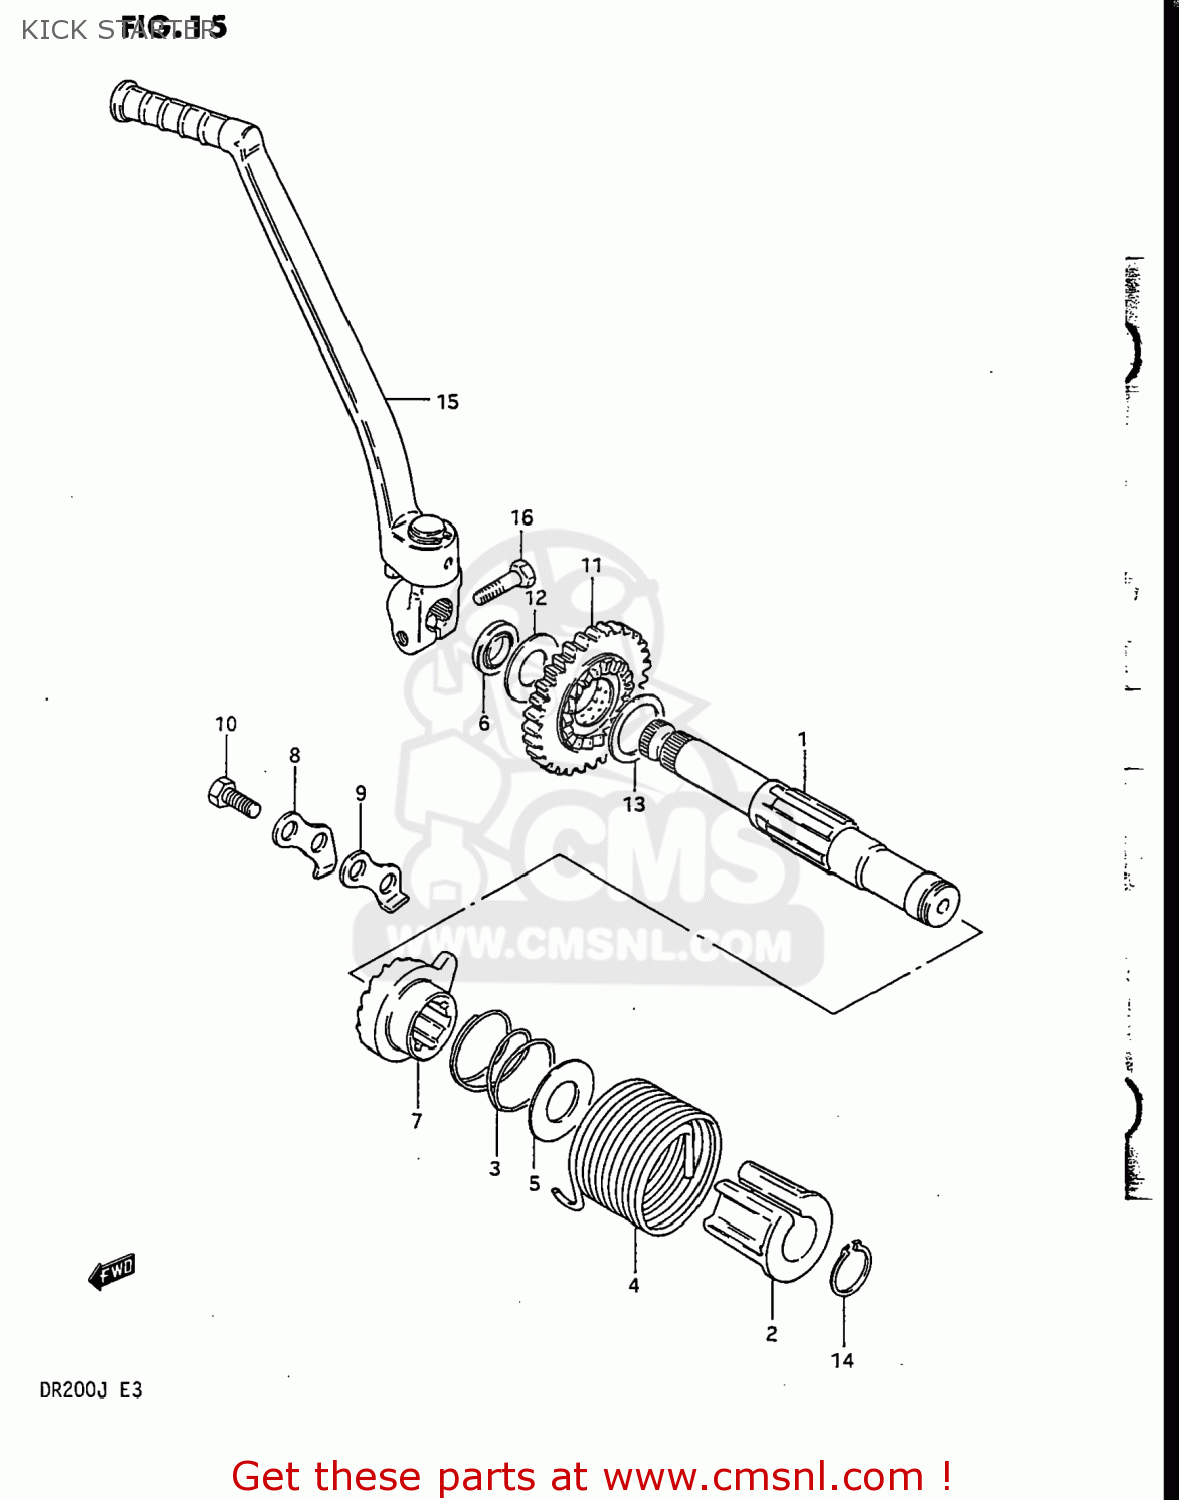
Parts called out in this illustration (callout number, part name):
1	SHAFT,KICK STARTER
2	GUIDE,KICK STARTER SFT SPRING
3	SPRING
4	SPRING
5	WASHER
6	SEAL,OIL(16X24X5)
7	STARTER,KICK
8	GUIDE,KICK STARTER
9	STOPPER,KICK STARTER
10	BOLT
11	GEAR,KICK STARTER DRIVE
12	WASHER(16X30X1)
13	WASHER
14	CIRCLIP
15	LEVER ASSY,KICK STARTER
16	BOLT 8X25
